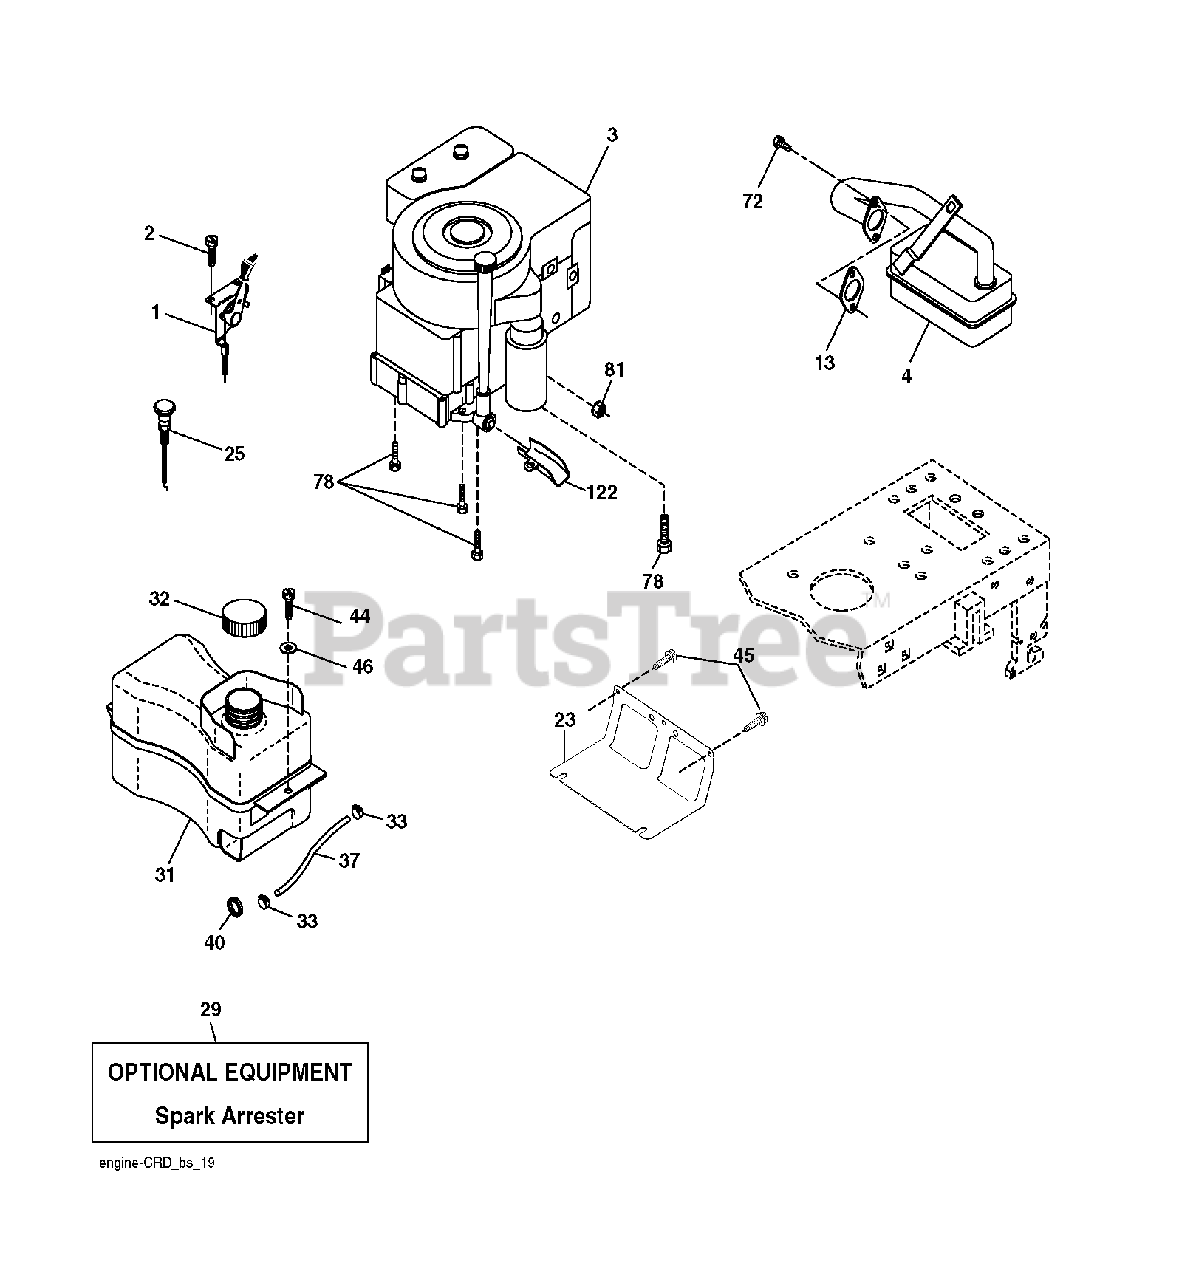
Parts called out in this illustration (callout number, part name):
1	CONTROL TH/CH FLAG
2	SCREW
13	REPL BY 532 27 22-93
23	SHEILD.BROWNING.DBR.GUARD
25	KNOB.ERGO.EXTENDED.RED (1 2)
29	ARRESTER SPARK (OPTIONAL)
32	CAP ASM.FUEL.2.25"FR.
44	SCREW HEXWSHR 1/4-20X3/4
45	SCREW, 3/8-16X3/4
72	SCREW.SOCKET HD.5/16-1
81	NUT
122	EXTENSION DRAIN OIL
